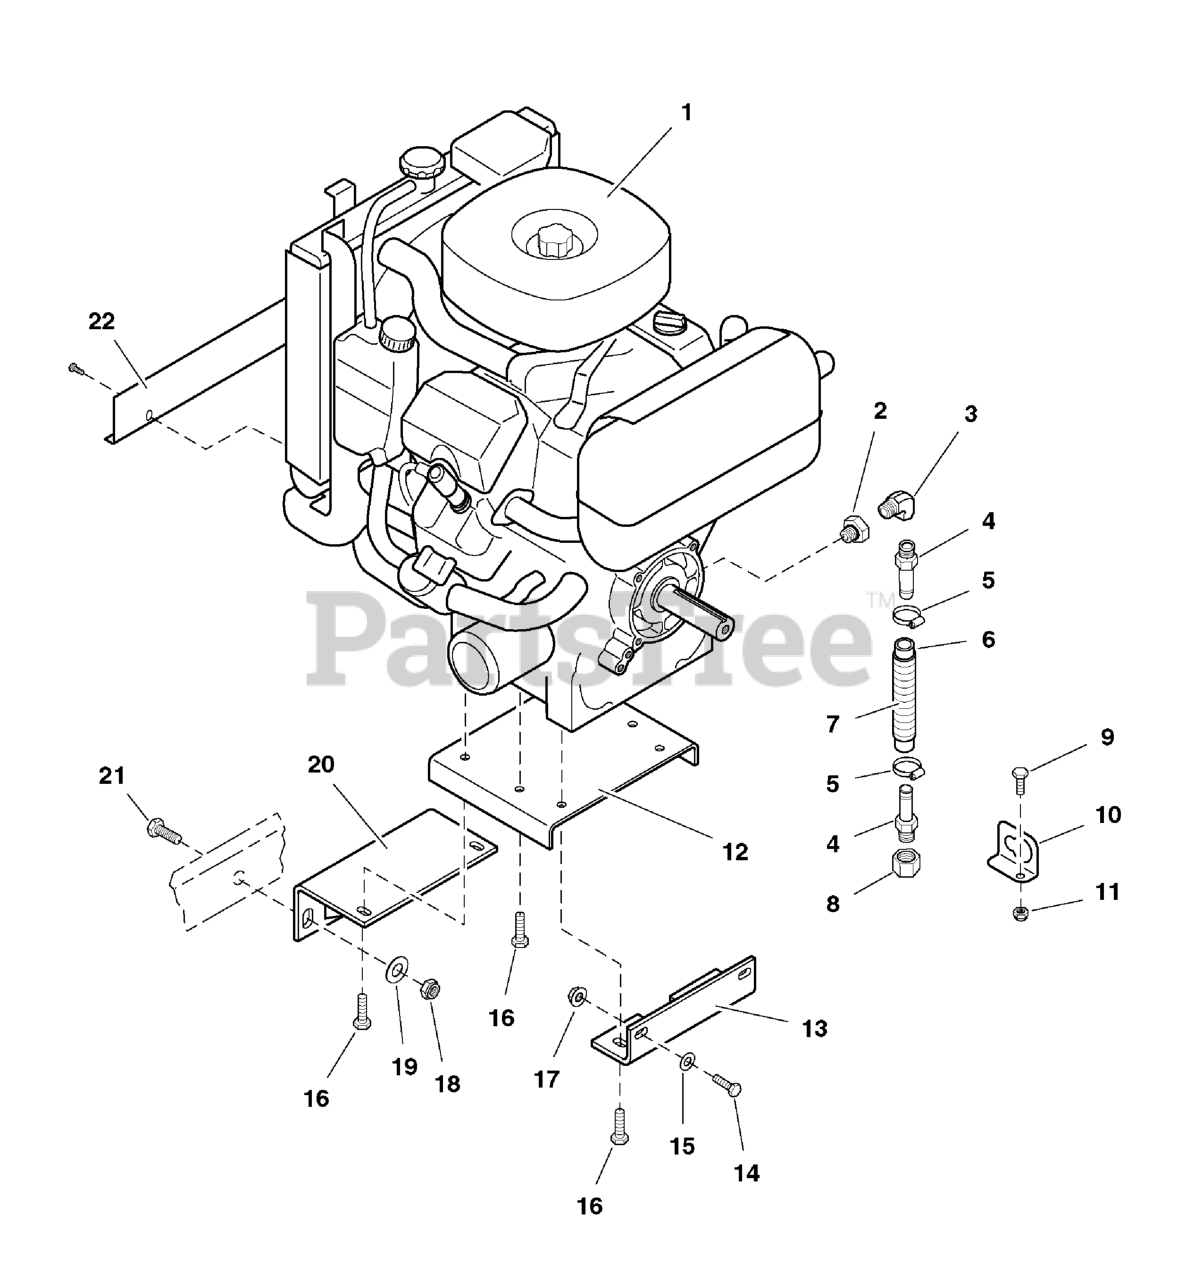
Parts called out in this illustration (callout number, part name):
2	FITTING, Oil Drain Adapter
3	FITTING, 3/8NPT Elbow
4	FITTING, 3/8NPT-1/2" Hose, Straight
5	CLAMP, #6 Hose
6	HOSE, 7"
7	WIRE LOOM, 6"
8	CAP, 3/8 NPT
9	BOLT, 5/16-18 X 3/4 GD5
10	ANCHOR, Oil Drain
11	NUT, 5/16-18 Hex Nylon Lock
12	PLATE, Engine Mount
13	SUPPORT, Engine Plate
14	BOLT, 3/8-16 X 1-1/2" GD5 CZ
15	WASHER, 3/8 SAE
16	BOLT, M10 x 25MM
17	NUT, 3/8-16 Hex Serrated Flange
18	NUT, Hex, Nylon Lock, 1/2-20
19	WASHER, 1/2 SAE
20	MOUNT, Engine Plate
21	BOLT, 1/2-20 X 1-1/2, GD5 CZ
22	BAFFLE, Radiator
